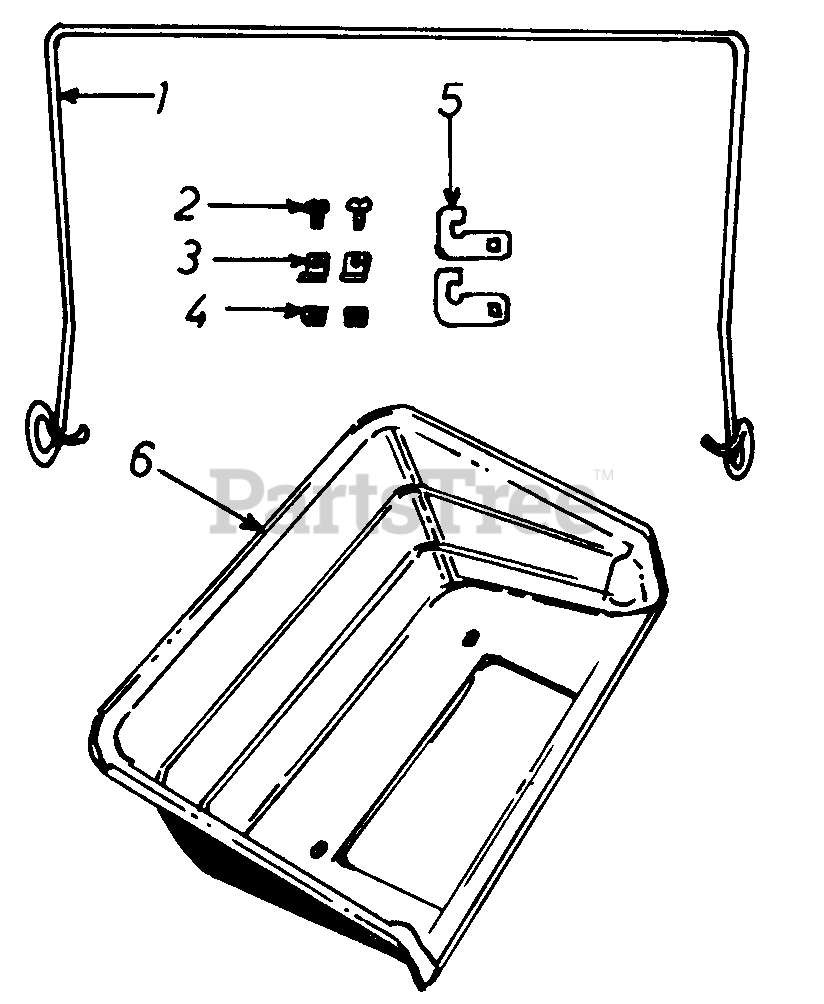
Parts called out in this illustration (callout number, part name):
1	Spring Mounting Loop
2	Truss Sems Scr. #10-24 x 3/8 " Lg.
3	Speed Clamp
4	Square nut #10-24
5	Mounting Hook
6	Grass Catcher
